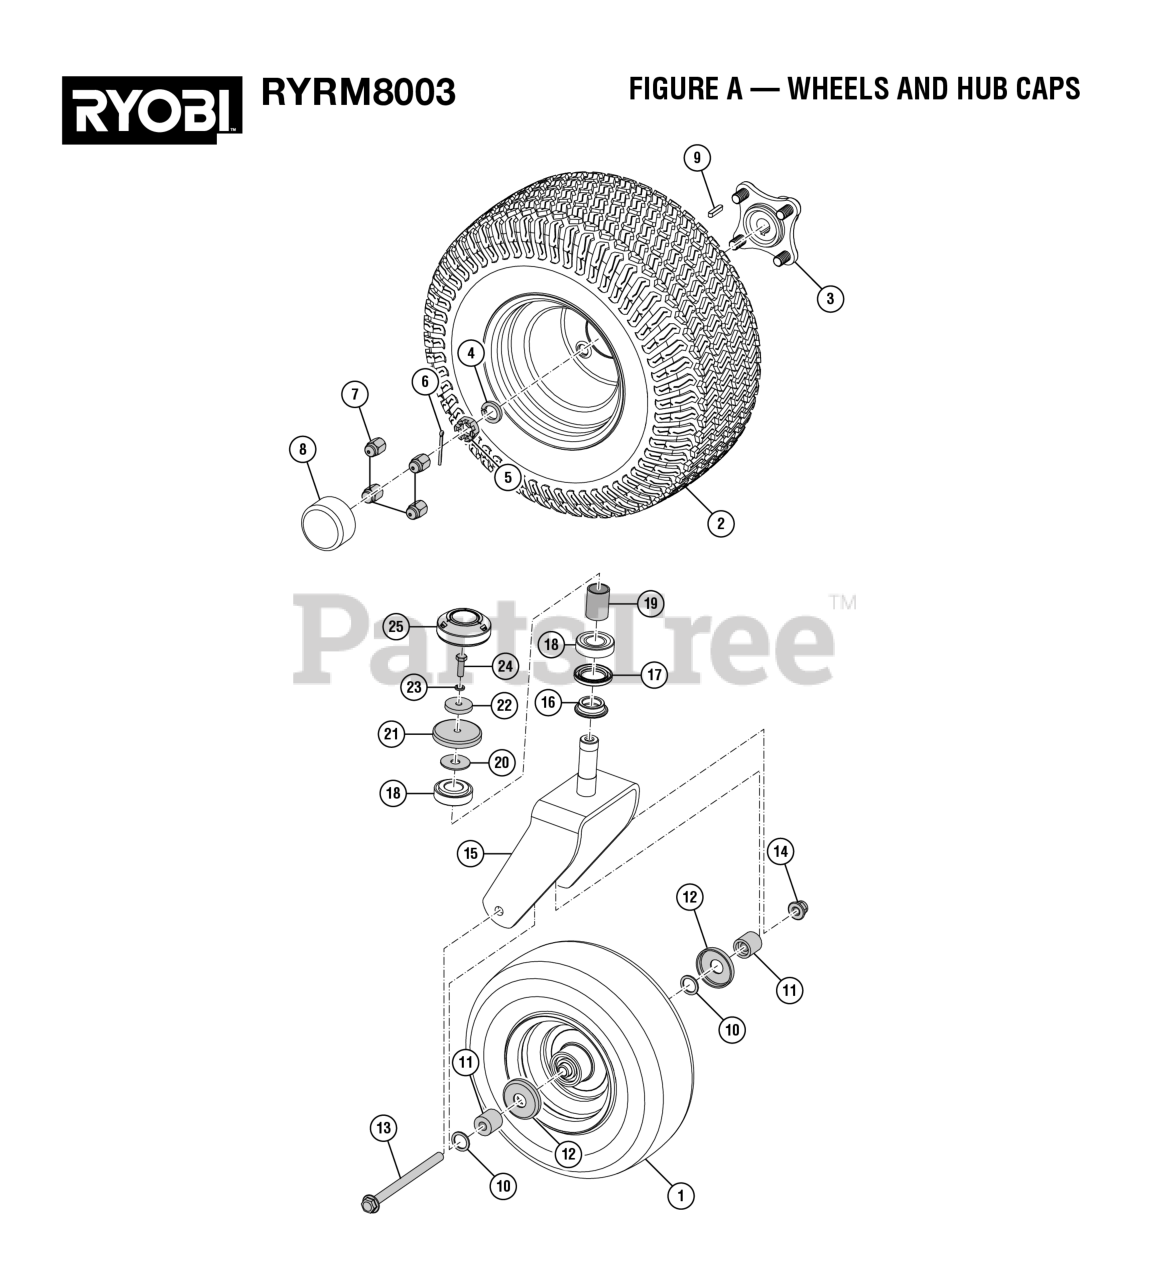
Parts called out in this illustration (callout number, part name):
1	Caster Wheel
3	Wheel Hub
4	Lock Spring Washer (20.6 x 30.6 x 4.8t)
5	Castle Nut (M20)
6	Drive Shaft Cotter Pin
7	Acorn Nut (M14)
8	Wheel Hub Cover
9	Key (6 mm x 6 mm x 30 mm)
10	Washer (OD28 x ID20.5 x 2t)
11	Caster Wheel Spacer
12	Front Wheel Bearing Cover
13	Flange Bolt (M12 x 170 mm, Hex Hd.)
14	Flange Nut (M12)
15	Caster Fork
16	Bearing Assembly Base
17	Rubber Seal
18	Roller Bearing (ID 25 mm x OD 52 mm)
19	Bearing Assembly Spacer
20	Fender Washer (OD40 x ID12.5 x 2t)
21	Bearing Assembly Cap
22	Fender Washer (OD37 x ID8.4 x 6t)
23	Lock Washer (OD9.8 x ID8.5 x 5t)
24	Bolt (M8 x 25 mm, Hex Hd.)
25	Caster Fork Cover
